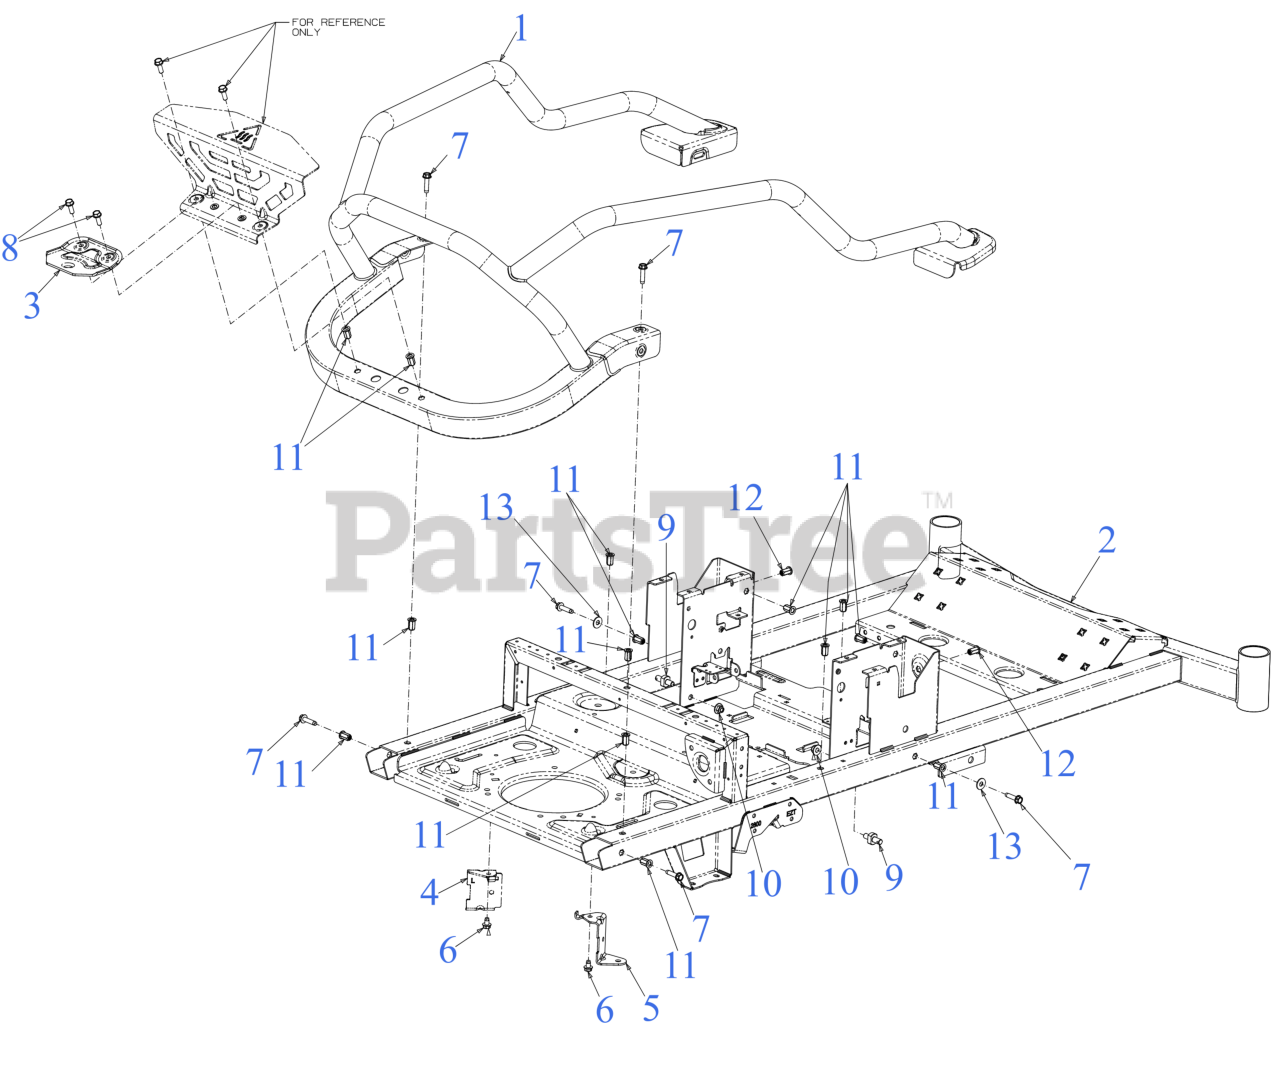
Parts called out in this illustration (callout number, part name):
1	UPPER FRAME
2	FRAME
3	HITCH PLATE
4	TRANSMISSON MOUNT SUPPORT (LH)
5	TRANSMISSON MOUNT SUPPORT (RH)
6	SCREW 5/16-18 x .500
7	SCREW 5/16-18 x 1.25
8	SCREW 5/16-18 x .875 GR5
9	SHOULDER STUD
11	NUT RIVET 5/16-18
12	NUT RIVET 5/16-18
13	FLAT WASHER
